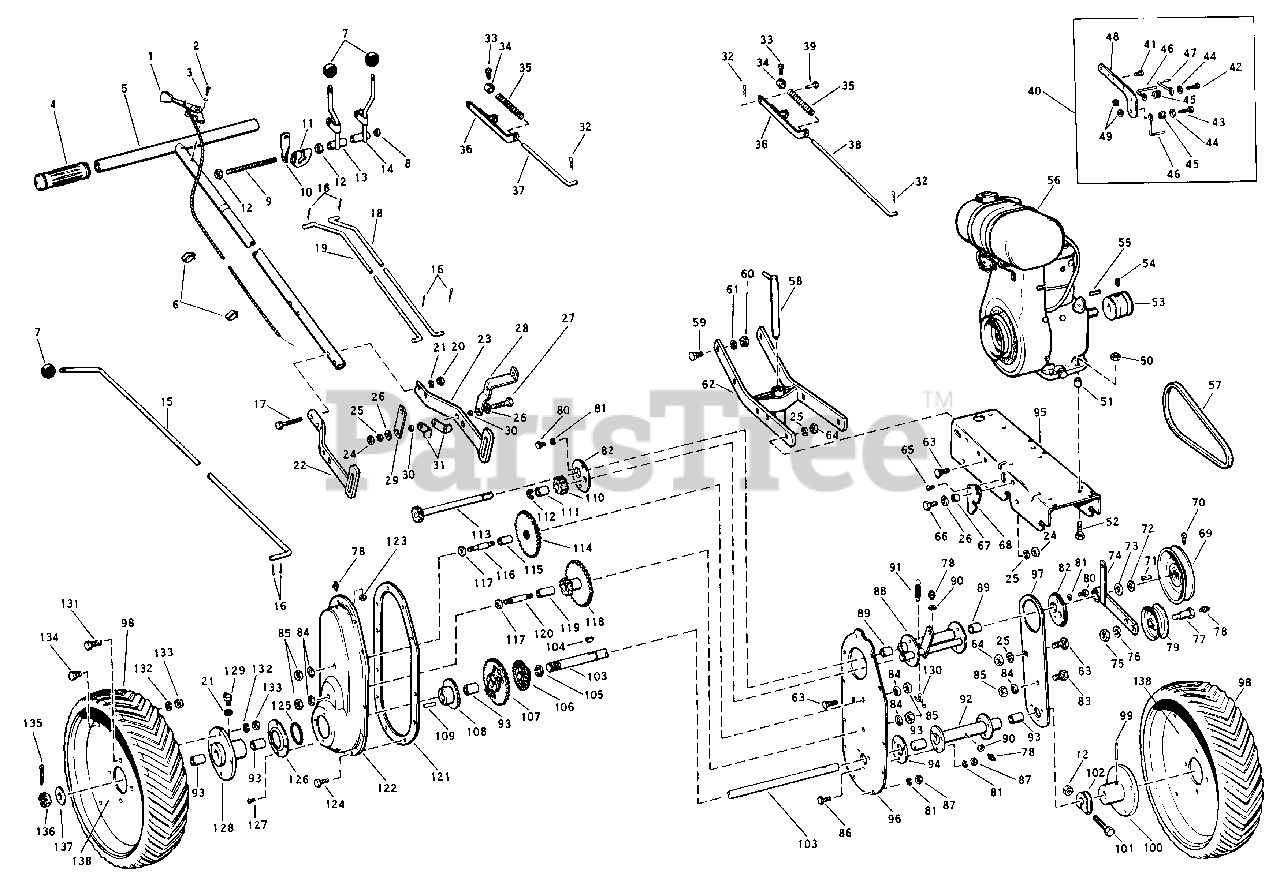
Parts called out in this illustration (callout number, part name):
1	Throttle Cable Assembly
2	Machine Screw #10-32 x 3/8 Lg.
3	Lockwasher #10
5	Handle Bar Tube Assembly
6	Cable Clip
7	Knob 5/16-18
8	Retaining Ring Truarc 5555-37
9	Control Shaft
10	Shift Rod Support
12	Hex Nut 3/8-24
13	Control Lever Assembly RH
14	Control Lever Assembly LH
15	Shift Rod
16	Cotter Pin 3/32 x 3/4 Lg.
17	Hex Hd. Capscrew 5/16-18 x 2 Lg.
18	Control Rod LH
19	Control Rod RH
20	Hex Nut 5/16-18
21	Lockwasher 5/16
22	RH Handle Bar Bracket Assy.
23	LH Handle Bar Bracket Assy.
24	Hex Jam Nut 3/8-16
25	Lockwasher 3/8
26	Washer 3/8
27	Hex Head Capscrew 3/8-16 x 1-1/2 Lg.
28	Implement Lever
29	Clutch Lever
30	Spacer 5/8 x 3/8 ID x 7/32 Lg.
31	Stop Lever
32	Spring Clip
33	Set Screw
34	Set Collar
35	Control Spring
36	Spring Bracket Assembly
37	Transmission Control Spring Rod
38	Implement Control Spring Rod
40	Belt Guide Assembly
41	Machine Screw and Washer 5/16-18 x 1/2 Lg.
42	Hex Head Capscrew 5/16-18 x 1-1/4 Lg.
43	Hex Head Capscrew 5/16-18 x 1-1/8 Lg.
44	Washer 5/16
46	Belt Guide
47	Front Belt Guide
48	Belt Guide Bracket
49	Hex Jam Nut 5/16-18
50	Nut and Washer 5/16-18
52	Hex Head Capscrew 5/16-18 x 1-1/4 Lg.
53	Engine Sheave, 2 Groove 2-1/4 OD
54	Set Screw 5/16-18 x 1/4 Lg.
55	Key 3/16 Sq. x 1-1/8 Lg.
56	Engine, Clinton B-1290
57	"V" Belt 36" A Section
58	Hitch Pin Assembly
59	Carriage Bolt 3/8-16 x 1 Lg.
60	Hex Nut 3/8-16
61	Lockwasher 3/8
62	Frame Assembly
63	Carriage Bolt 3/8-16 x 1-1/4 Lg.
64	Hex Nut 3/8-16
65	Drive Screw #10 x 3/8 Lg. P-K Type U
66	Hex Head Capscrew 3/8-16 x 3/4 Lg.
67	Spacer 3/8 ID x 5/8 OD x 1/8 Thick
68	Hitch Latch
69	Pulley 5.4 OD x 5/8 Bore
70	Set Screw 5/16-18 x 5/8 Lg.
71	Key 3/16 Sq. x 3/4 Lg.
72	Retaining Ring Truarc 5100-62
74	Idler Pulley Lever Assembly
75	Hex Jam Nut 1/2-20
76	Lockwasher 1/2
77	Idler Pulley Shaft
78	Grease Fitting 1/4-28 Straight
79	Idler Pulley
80	Capscrew 1/4-28 x 1/2 Lg.
81	Lockwasher 1/4
82	Pilot Assembly
83	Hex Head Capscrew 7/16-14 x 3/4 Lg.
84	Lockwasher 7/16, Shakeproof
85	Hex Jam Nut 7/16-14
86	Hex Head Capscrew 1/4-20 x 5/8 Lg.
87	Hex Nut 1/4-20
88	Input Tube and Idler Shaft Assy.
89	Bushing (Oilite)
90	Lockwasher 1/4
91	Shift Rod Spring
92	Axle Tube Assembly
93	Bushing (Oilite)
94	Axle Tube Gasket 1/32 Thick
95	Engine Mount
96	Back Plate
97	Left Support Plate
98	Tire 4 x 16
99	Roll Pin 1/4 x 1-3/4 Lg.
100	Left Wheel Hub
101	Hex Head Capscrew 3/8-24 x 2 Lg.
104	Woodruff Key #505
105	Retaining Ring, 3/4 Shaft, Truarc 5100-75
106	Left Differential Gear
107	Final Drive Gear and Differential Pinion Assembly
108	Right Differential Gear
109	Roll Pin 1/4 x 1-1/8 Lg.
110	Idler Pinion Assembly
111	Bushing (Oilite)
112	Retaining Ring
113	Input Gear Assembly
114	First Intermediate Gear and Pinion Assembly
115	Bushing (Oilite)
116	First Intermediate Shaft
118	Second Intermediate Gear and Pinion Assembly
119	Bushing (Oilite)
120	Second Intermediate Shaft
121	Gear Case Cover Gasket
122	Gear Case Cover
123	Hex Jam Nut 1/4-28
124	Hex Head Capscrew 1/4-20 x 1/2 Lg.
125	Ring (Neoprene)
126	Oil Seal Retainer
127	Self Tapping Screw #8-32 x 1/4 Lg.
128	Right Wheel Hub Assembly
129	Grease Fitting 5/16-32
130	Spring Anchor
131	Hex Hd. Capscrew 5/16-18 x 1 Lg.
132	Lockwasher 5/16
133	Hex Nut 5/16-18
134	Hex Head Capscrew 5/16-18 x 5/8 Lg.
135	Cotter Pin 1/8 x 1-1/2 Lg.
136	Slotted Hex Nut 3/4-10
137	Washer 3/4
138	Half Wheel Rim
